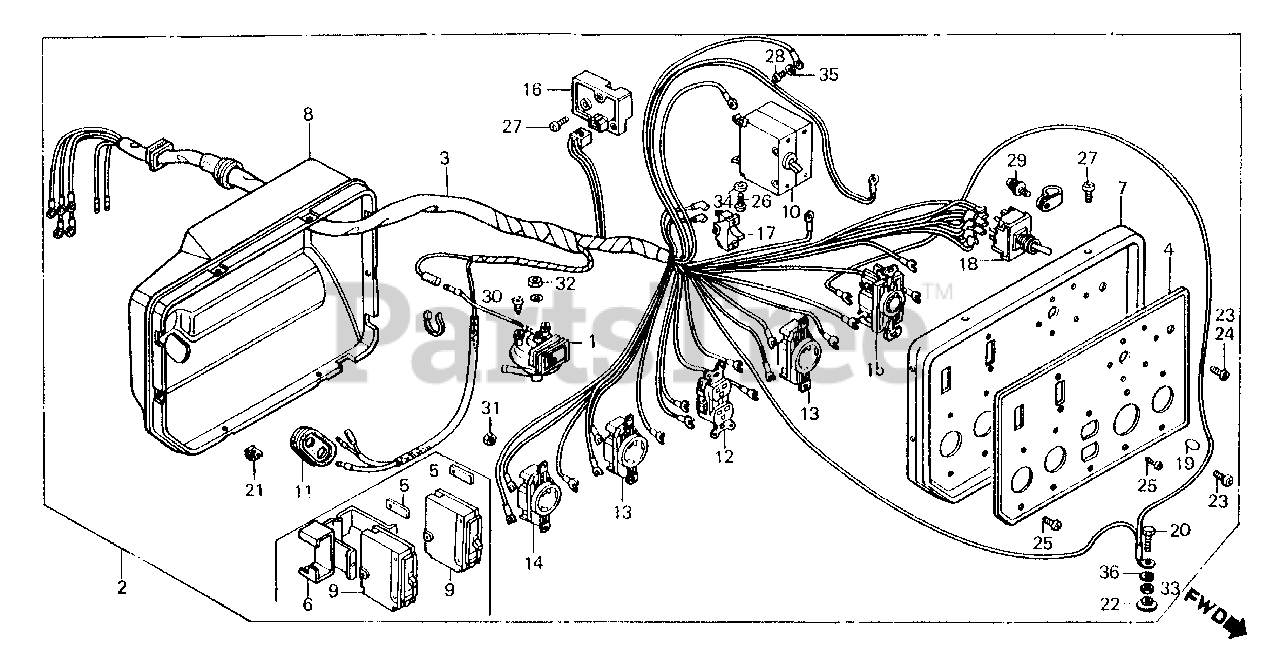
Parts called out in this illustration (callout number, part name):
1	SWITCH ASSY., UNIT
2	BOX ASSY., CONTROL *R8* (BRIGHT RED)
3	WIRE HARNESS ASSY. (NOT AVAILABLE)
3	WIRE HARNESS ASSY.
4	MARK, SWITCH PANEL (NOT AVAILABLE)
4	MARK, SWITCH PANEL
5	TERMINAL, BREAKER
6	SUPPORT, BREAKER
7	PANEL, CONTROL *R8* (BRIGHT RED)
7	PANEL, CONTROL
8	CASE, CONTROL
9	BREAKER, CIRCUIT (12.5A) (NOT AVAILABLE)
10	BREAKER, CIRCUIT (12.5A) (NOT AVAILABLE)
11	GROMMET, UNIT SWITCH
12	RECEPTACLE ASSY. (125V-20A)
12	RECEPTACLE (20A/125V)
13	RECEPTACLE (20A-125V)
14	RECEPTACLE (3-PRONG) (30A/125V)
15	RECEPTACLE (20A/125-250V)
16	CONTROL UNIT, IDLE
17	SWITCH ASSY., IDLE CONTROL (NOT AVAILABLE)
18	SWITCH ASSY., VOLT CHANGE
19	MARK, GROUND
20	BOLT, HEX. (6X18)
21	NUT, SPRING (5MM)
22	NUT, SPECIAL (6MM)
23	SCREW, PAN (3X6)
24	SCREW, PAN (4X6)
25	SCREW, PAN (4X8)
26	SCREW, PAN (4X10)
27	SCREW, PAN (5X12)
28	SCREW, PAN (5X12)
29	SCREW-WASHER (5X10)
30	SCREW, TAPPING (5X10)
31	NUT, HEX. (4MM)
32	NUT, HEX. (5MM)
33	NUT, HEX. (6MM)
34	WASHER, SPRING (4MM)
35	WASHER, SPRING (5MM)
36	WASHER, SPRING (6MM)
